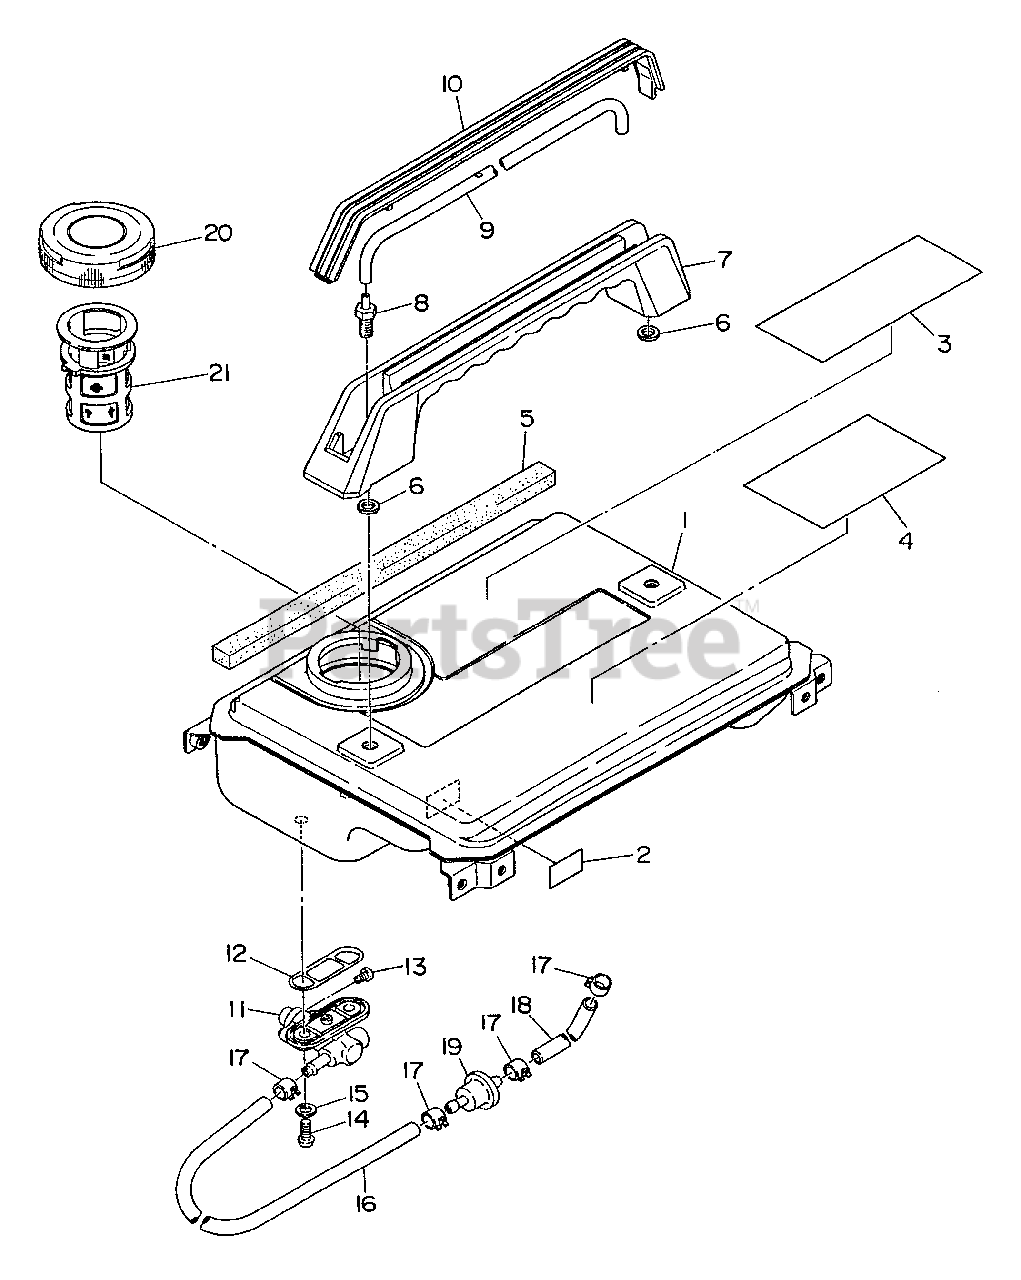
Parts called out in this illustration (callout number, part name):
1	FUEL TANK ASSY
2	FELT, tank
3	LABEL - CAUTION
4	LABEL - DANGER
5	SEAL, TANK
6	O-RING
7	HANDLE ASSY
8	BOLT, TANK
9	PIPE - BREATHER
10	COVER, HANDLE
11	FILTER, FUEL
12	GASKET
13	BOLT
14	SCREW
15	GASKET - FELT
16	RUBBER PIPE (4.5 dia. X 11 dia. X 160mm)
17	CLAMP, HOSE
18	RUBBER PIPE (4.5 dia. X 11 dia. X 160mm)
19	FILTER, FUEL
20	CAP ASSY
21	FILTER, FUEL
